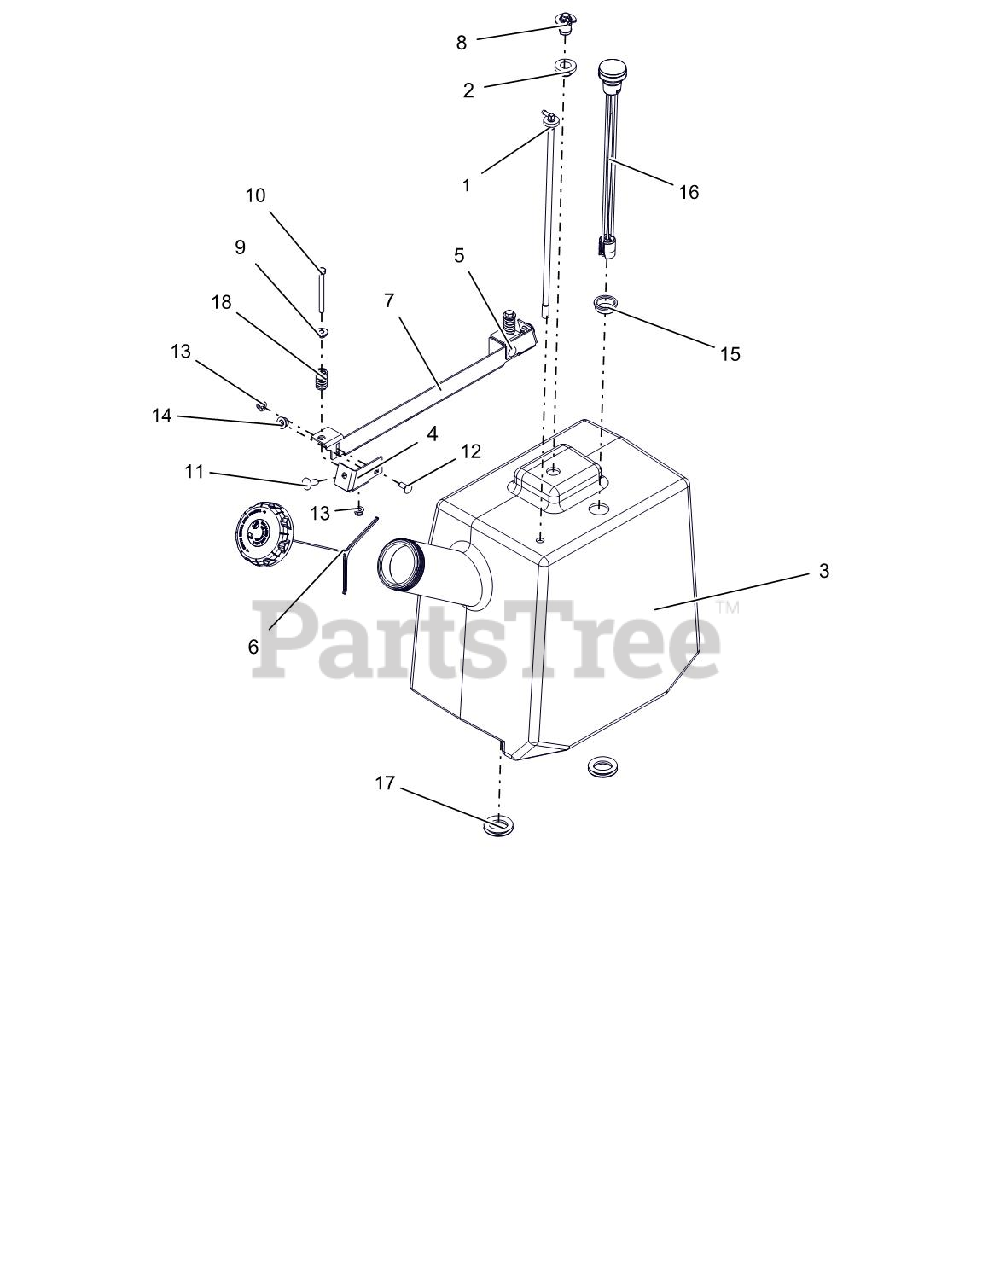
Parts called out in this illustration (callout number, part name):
1	ASS'Y, PROSTANCE FUEL PICK-UP
2	GROMMET, REMOTE VENT NITRILE
3	TANK, PROSTANCE FUEL
4	MOUNT, FUEL TANK HOLD DOWN-RH
5	MOUNT, FUEL TANK HOLD DOWN-LH
6	CAP, FUEL VENTIN AUTOLOCK
7	HOLDDOWN, FUEL TANK
8	VALVE, 2-WAY
9	BSHG-FLG .32X.500X.344X.880
10	@BLT-HEX .31-18X3.25 GR5 YWZC
11	@BLT-RDHDSHSQNK.38-16X1.0 G5YZ
12	@BLT-RDHDSQNK .31-18X.75 G5YZ
13	@NUT-LK-NYL-FLG .31-18 YWZC
14	@NUT-LK-NYL-FLG .38-16 YWZC
15	GROMMET, FUEL GAUGE
16	GAUGE, REMOTE FUEL SEALED 15"
17	GROMMET 1.25ID X 1.5OD
18	SG-COMP .125X.781X1.250
